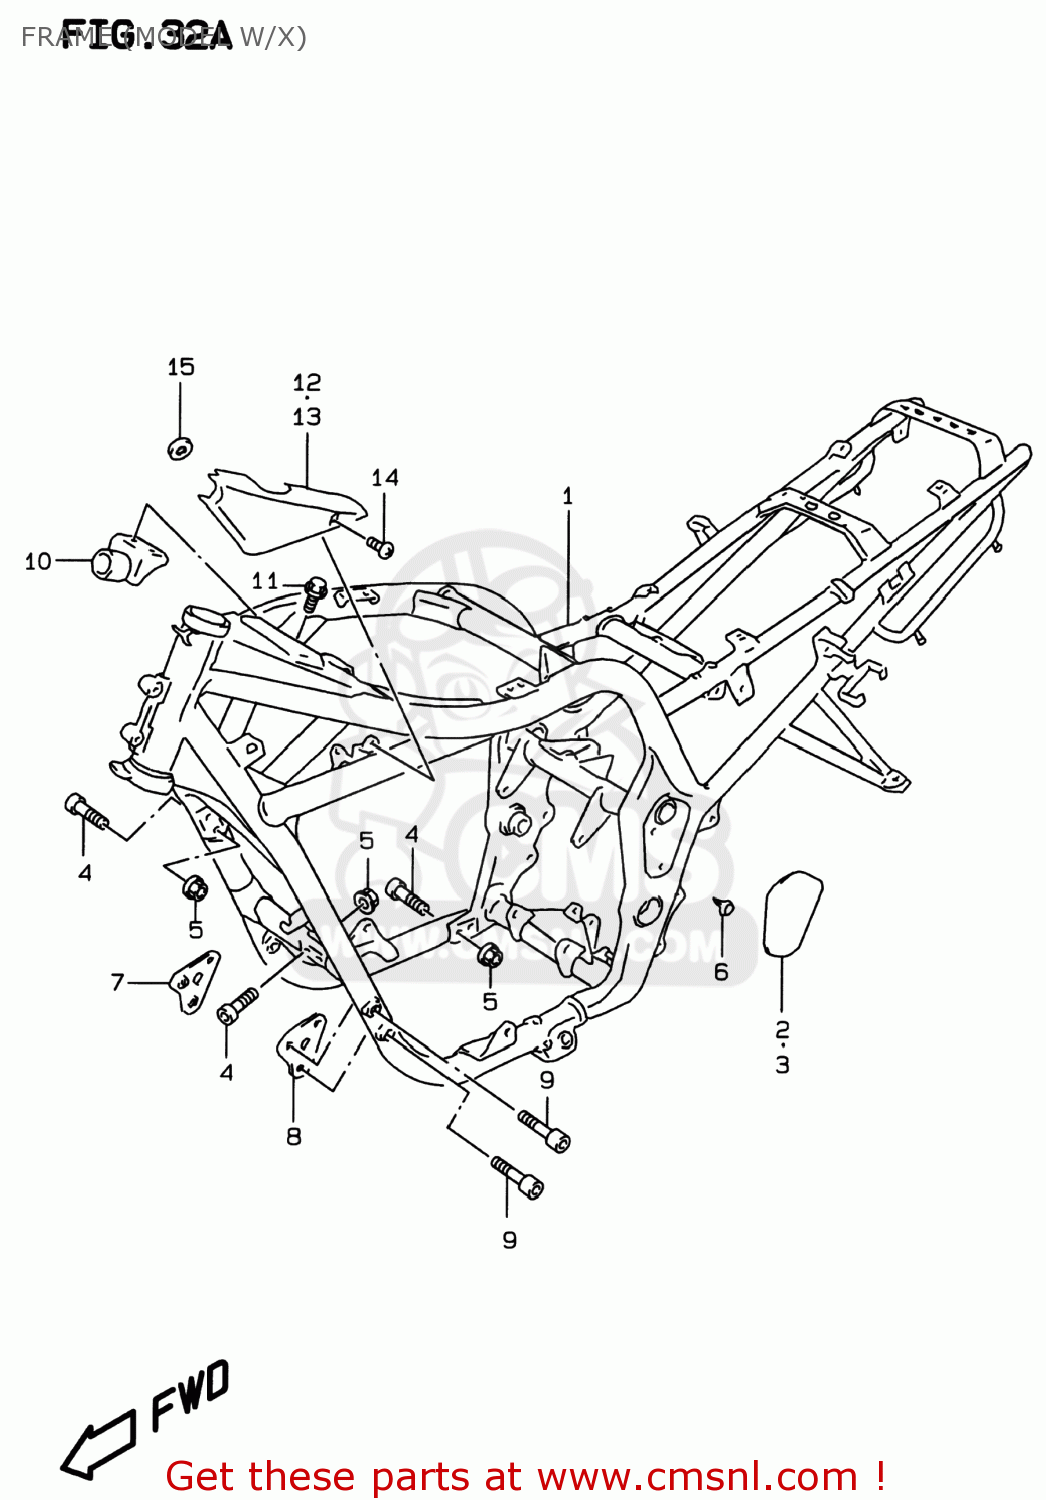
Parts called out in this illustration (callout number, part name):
1	FRAME(ORANGE)
2	COVER,FRAME BODY,R
3	COVER,FRAME BODY,L
4	BOLT(10X33)
5	NUT
6	CLIP
7	PLATE COMP,ENGINE MOUNTING
8	PLATE,ENG MTG,L
9	BOLT
10	DAMPER,FRAME
11	BOLT
12	COVER,FRAME HEAD,R
13	COVER,FRAME HEAD,L
14	SCREW(5X12)
15	CUSHION
